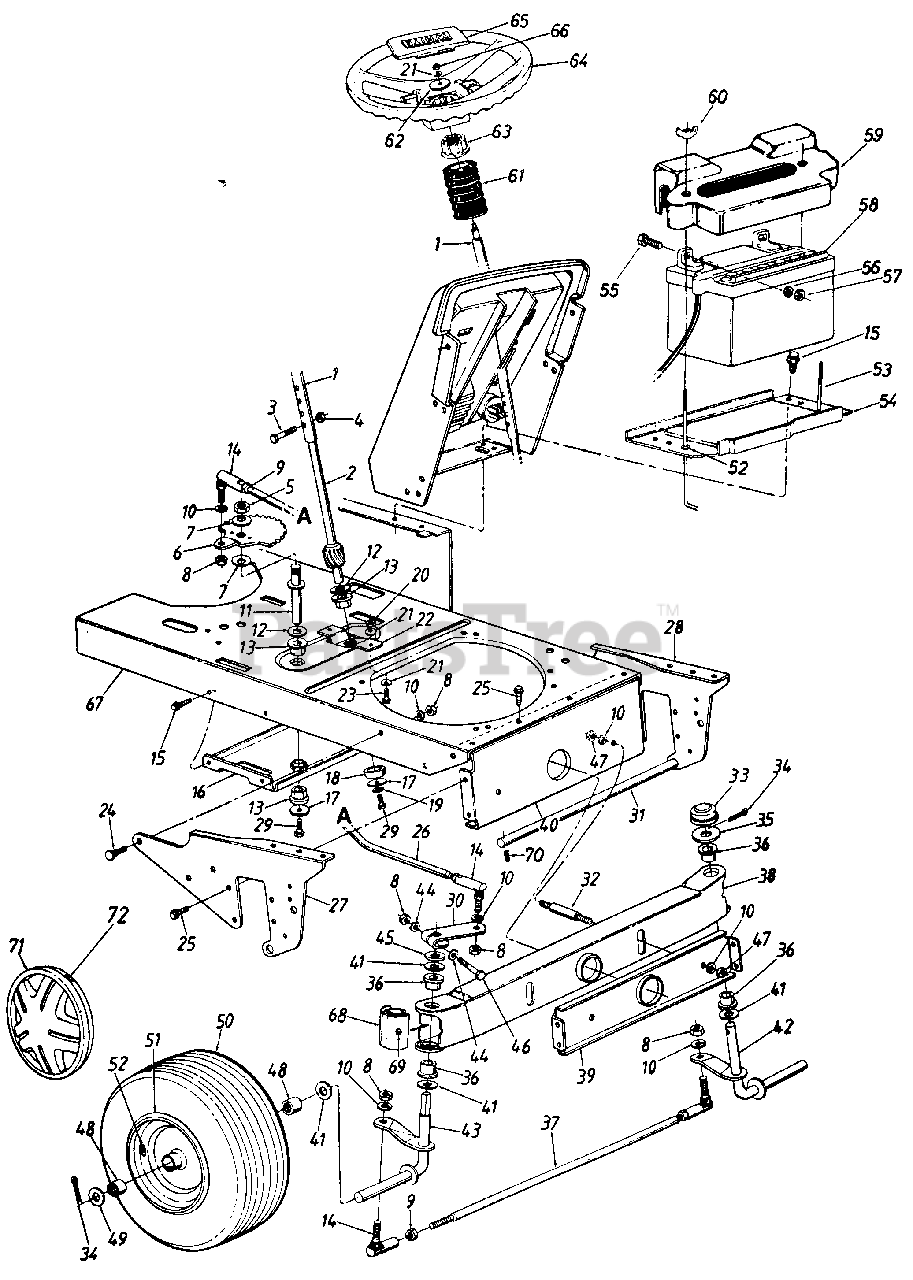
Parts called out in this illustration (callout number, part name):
1	Steering Column Ass'y.
2	Lower Steering Shaft
3	Hex Bolt 1/4-20 X 1.31" Lg.
4	Hex L-Nut 1/4-20 Thd.
5	Hex Nut 5/8-18 Thd.
6	Steering Gear Segment
7	Bell-Wash. 5/8" I.D. x 1.25" O.D.
8	Hex Nut 3/8-24 Thd.
9	Hex Jam Nut 3/8-24 Thd.
10	L-Wash. 3/8" I.D.
11	Steering Gear Segment Shaft
12	Fl-Wash. .64" I.D. x 1.24" O.D.
13	Hex Flange Brg. .63" I.D.
14	Ball Joint Ass'y.
15	Hex Wash. Hd. TT-Tap Scr. 1/4-20 x .5" Lg.
16	Deck Idler Support Brkt.
17	Fl-Wash. .33" I.D. x 1.25" O.D.
18	Spacer.985" I.D. x 1.25" O.D.
19	L-Wash. 5/16" I.D.
20	Hex Nut 5/16-24 Thd.
21	Bell-Wash. .345" I.D. x .88" O.D.
24	Ribbed Neck Bolt 3/8-24 x .8" Lg.
25	Hex Wash. TT-Tap Scr. 5/16-18 x .62" Lg.
26	Steering Drag Link
27	Pivot Bar Side Plate-R.H.
28	Pivot Bar Side Plate-L.H.
29	Hex Bolt 5/16-18 x .62" Lg.
30	Steering Arm
31	Deck Connecting Rod
32	Pivot Bar Shld. Bolt 3/8-16 x 5/8" Lg.
34	Cotter Pin 5/32" Dia.
35	Flat Washer
36	Flange Brg. .757" I.D.
37	Tie Rod 20.25" Lg.
38	Pivot Bar Assy.
41	Fl-Wash. .76" I.D. x 1.49" O.D.
42	Front Axle Ass'y.-L.H.
43	Front Axle Ass'y.-R.H.
44	Bowed Washer
45	Spacer .755" I.D. x 1.25" O.D.
46	Hex Bolt 3/8-24 x 2.25" Lg.
47	Hex Nut 3/8-16 Thd.
48	Needle Brg. .75" I.D.
49	Fl-Wash. .71" I.D. x 1.5" O.D.
50	Wheel Ass'y. Comp.
52	Push Nut
53	Battery Hold Down Rod
54	Battery Carrier
55	Hex Bolt 1/4-20 X .62" Lg.
56	L-Wash. 1/4" I.D.
57	Hex Nut 1/4-20 Thd.
58	Battery
59	Battery Cover
60	Wing Nut Plastic 1/4-20 Thd.
61	Steering Bellow
62	Flat Washer
63	Steering Wheel Adapter
64	Steering Wheel
65	Steering Wheel Cap
66	Hex L-Nut 5/16-24 Thd.
67	Lower Frame
68	Pivot Bar End Cap
69	Grease Fitting
70	Internal Cotter Pin
72	Spring Clip
